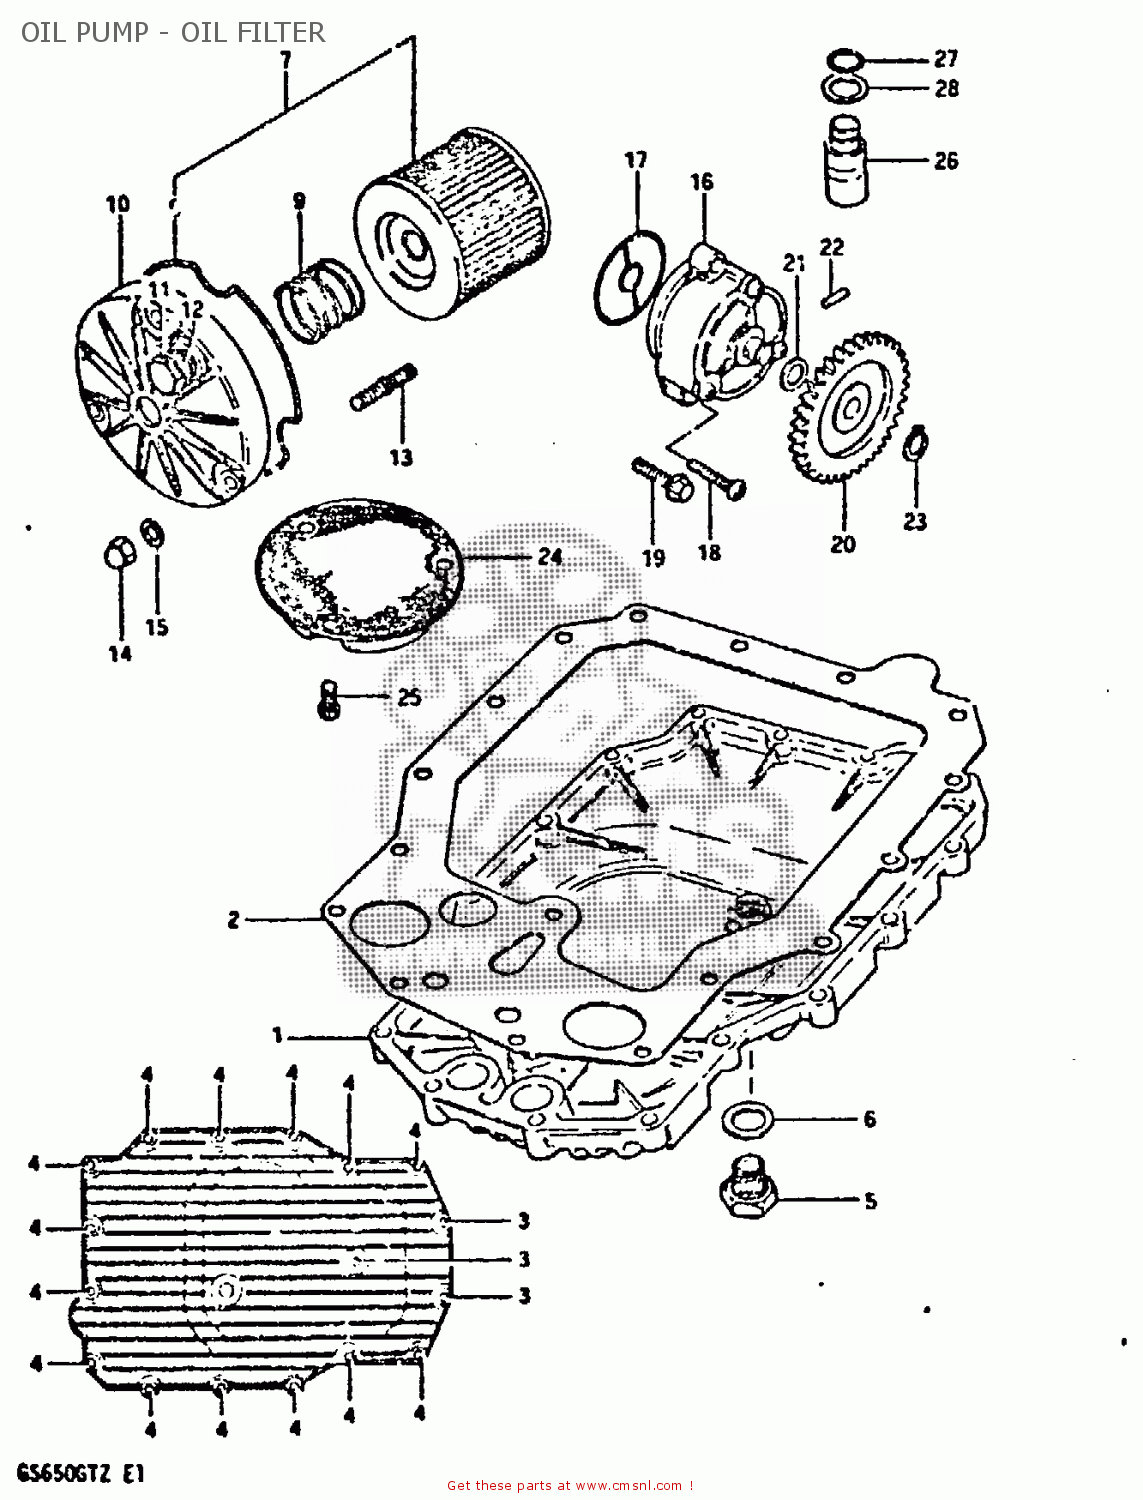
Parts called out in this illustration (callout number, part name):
1	PAN,OIL
2	GASKET,OIL PAN (MCA)
3	BOLT
4	BOLT
5	PLUG
6	GASKET(14X19.2X2) (NAS)
7	ENGINE OIL FILTER SET
8	O RING,OIL FILTER CHAMBER CAP
9	SPRING
10	CAP,OIL FILTER
11	PLUG
12	GASKET(14X19.2X2) (NAS)
13	STUD 6X20
14	NUT
15	WASHER
16	PUMP ASSEMBLY,OIL
17	O-RING,OIL PUMP
18	SCREW
19	BOLT
20	GEAR,OIL PUMP DRIVEN
21	SHIM
22	PIN(4X15.8)
23	CIRCLIP
24	STRAINER,ENGINE OIL
25	SCREW 6X12
26	REGULATOR ASSEMBLY,ENGINE
27	O-RING
28	WASHER
